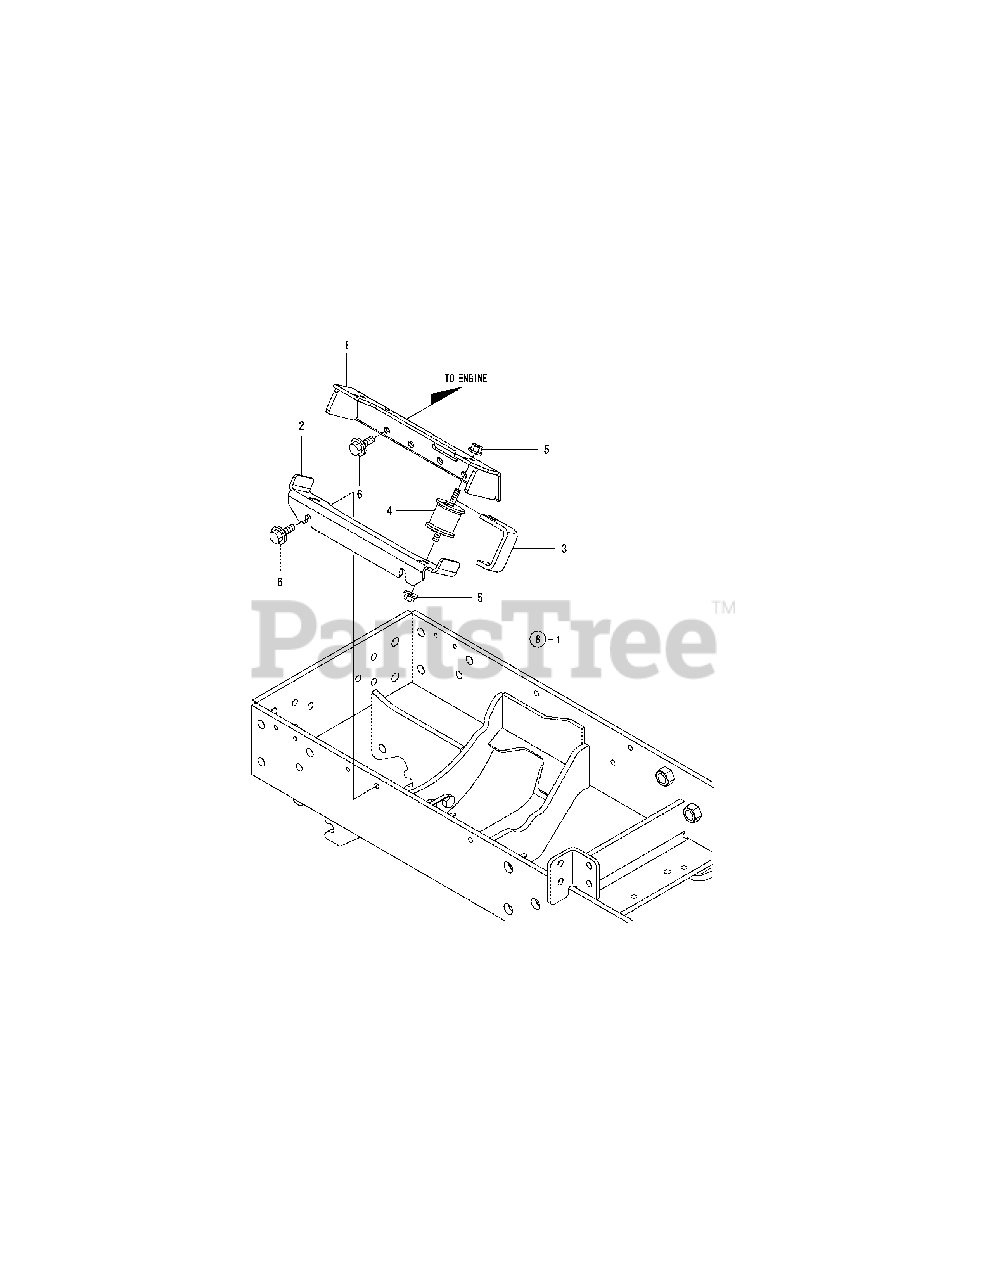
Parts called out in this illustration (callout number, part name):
1	STAY CMP, ENGINE
2	MOUNT STAY, FRAME
5	NUT W/WASHER 8
6	BOLT M10X 20 PLATED
